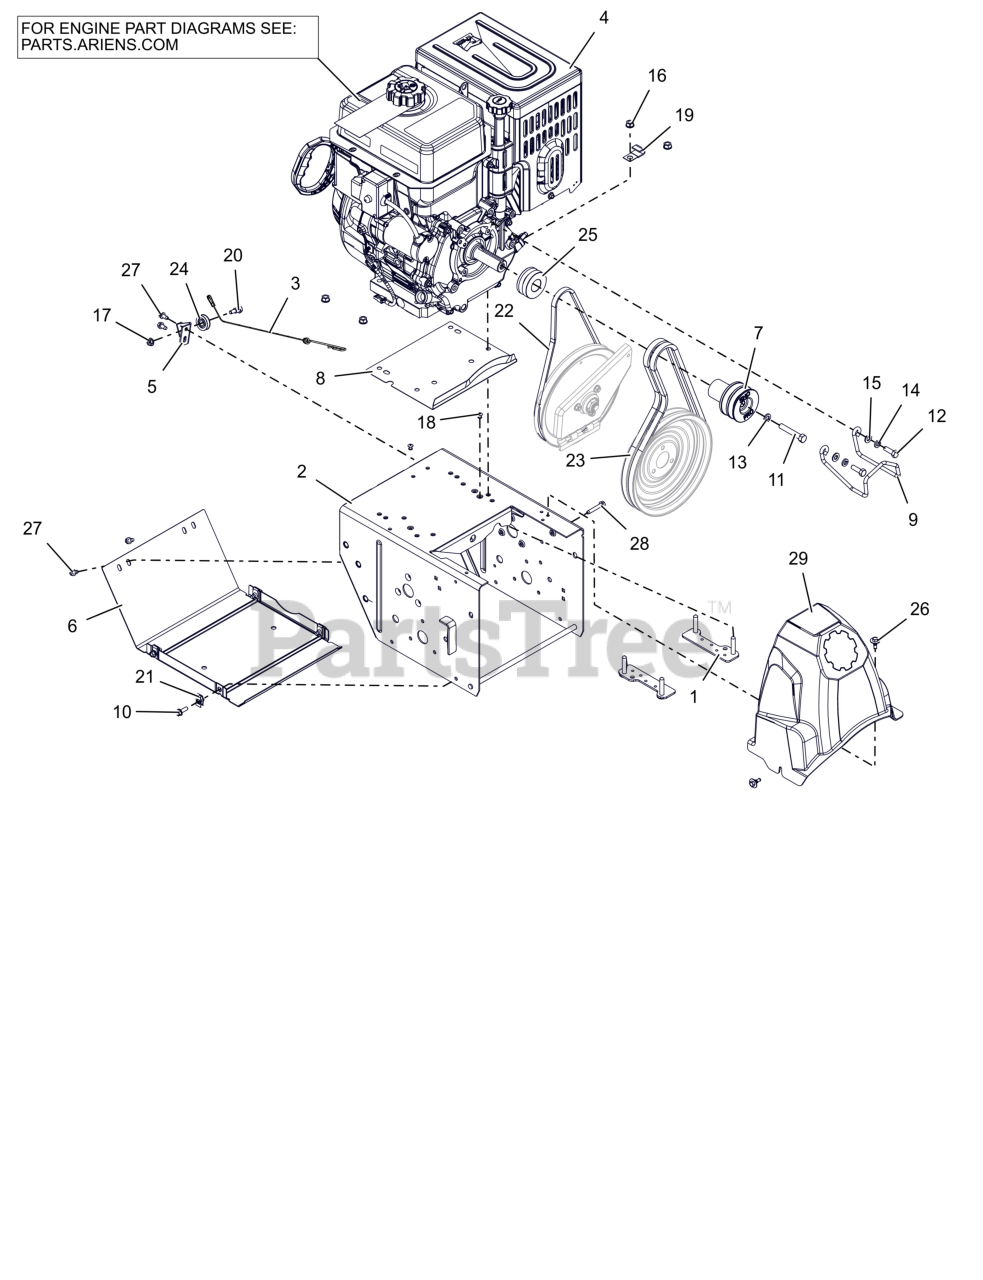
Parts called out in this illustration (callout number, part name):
1	STRAP, BOLT-LARGE
2	FRAME, MAIN - PRO (WELDMENT)
3	CABLE, LOWER TRACTION,SS & PRO
4	ENGINE, ARIENS AX420 120V/60W
5	BRKT, CABLE PULLEY
6	COVER, BOTTOM
7	SHEAVE,ATTACHMENT-SHO 2 GRV
8	BAFFLE, WATER - LARGE BLOCK (ORANGE)
9	FINGER, BELT
10	BLT, HWH .25-20X.75 G5 ZCC
11	BLT, HEX .38-24X2.25 G5 ZCC
12	BLT, HEX 0.3125-24X1 G5 ZCC
13	WSHR,LK-REG .375X.094 ZCC
14	WSHR, LK-HVY .312X.097 ZCC
15	WSHR,FLT .344X.688X.065 ZCC
16	NUT,LK-CTR-FLG .31-18 GF ZCC
17	NUT-LK-TOP-FLG .250-20 GF ZCC
18	RVT, POP .1875 ZCC
19	J-CLAMP
20	BOLT, SHLDR -.375 X .375 X .25-20
21	NUT-RTNR .25-20X.56
22	V-BELT, 3L-WRAPPED
23	V-BELT, HA-RAW EDGE (SET)
24	PULLEY, CABLE
25	SHEAVE, TRACTION (KEYLESS)
26	SCR-TAP .25-20X.5 CAPTIVE
27	SCR-TAP .25-20X.50 HWH ZCC
28	SCR,TAP .25-20X1.50 HWH TR ZCC
29	COVER, BELT
